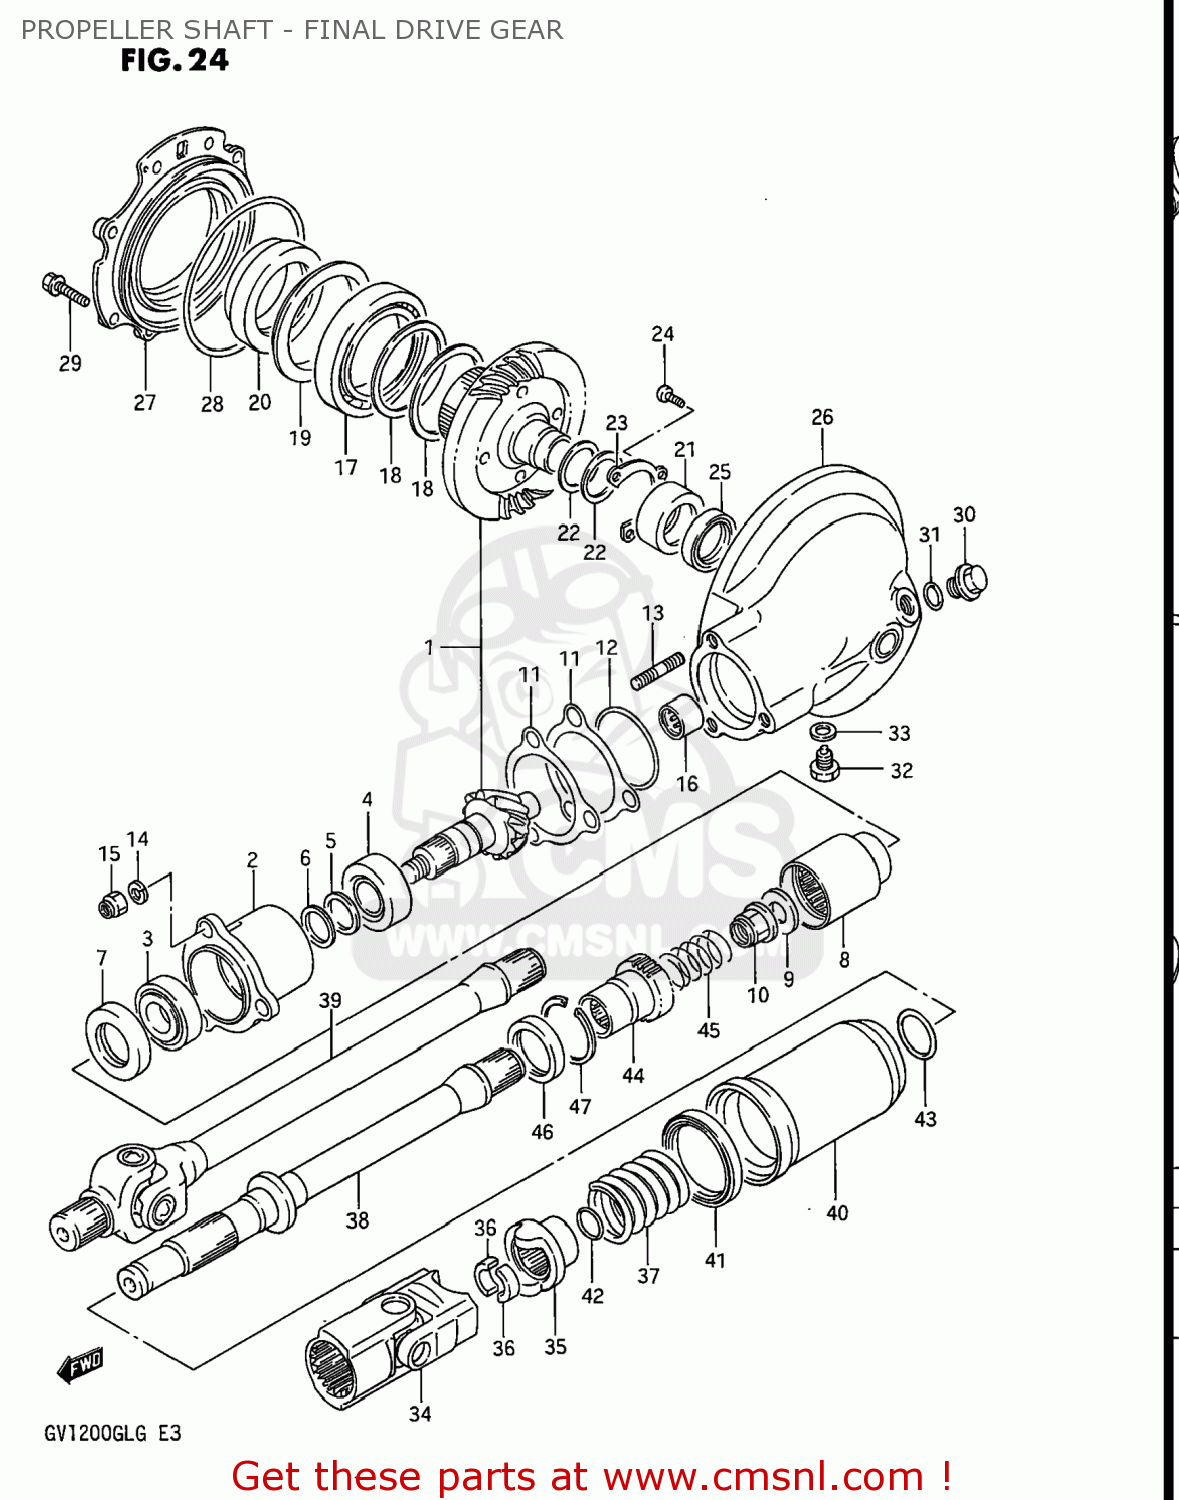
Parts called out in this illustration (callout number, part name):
1	GEAR SET,FINAL BEVEL
2	HOUSING,FINAL BEVEL GEAR
3	BEARING
4	BEARING(25X52X19.25)
5	SPACER
6	SHIM (25X30X2
7	SEAL,OIL(32X54X7)
8	GEAR,FINAL DRIVE
9	WASHER(14X29X4)
10	NUT
11	SHIM,DRIVE GEAR HOUSING
12	O RING(D:2.4,ID:62.6)
13	STUD 10X30
14	LOCK WASHER
15	NUT
16	ROLLER BEARING (18X25X2
17	BEARING(70X110X13)
18	SHIM,DRIVEN GEAR BEARING T0.35
19	PLATE,FINAL DRIVEN GEAR
20	SEAL,OIL(70X96X16)
21	BEARING(32X46X17.7)
22	SHIM,FINAL DRIVEN GEAR
23	RETAINER,FINAL DRIVEN GEAR BRG
24	SCREW 6X12
25	SEAL,OIL(30X42X7)
26	CASE,FINAL GEAR
27	CASE,FINAL GEAR BEARING
28	O-RING
29	BOLT
30	PLUG
31	O RING(D:2.4,ID:17.8)
32	PLUG
33	GASKET(14X19.2X2) (NAS)
34	YOKE,UNIVERSAL JOINT
35	DOG,OUTPUT CAM
36	STOPPER,CAM DOG
37	SPRING
38	SHAFT,PROPELLER
39	YOKE,UNIVERSAL JOINT
40	COVER,PROPELLER SHAFT DA
41	OIL SEAL
42	O RING(D:2.4,ID:15.8)
43	O RING(D:2,ID:23.5)
44	COUPLING,PROPELLER SHAFT
45	SPRING
46	SEAL,OIL(30X40.5X5.5)
47	CIRCLIP
